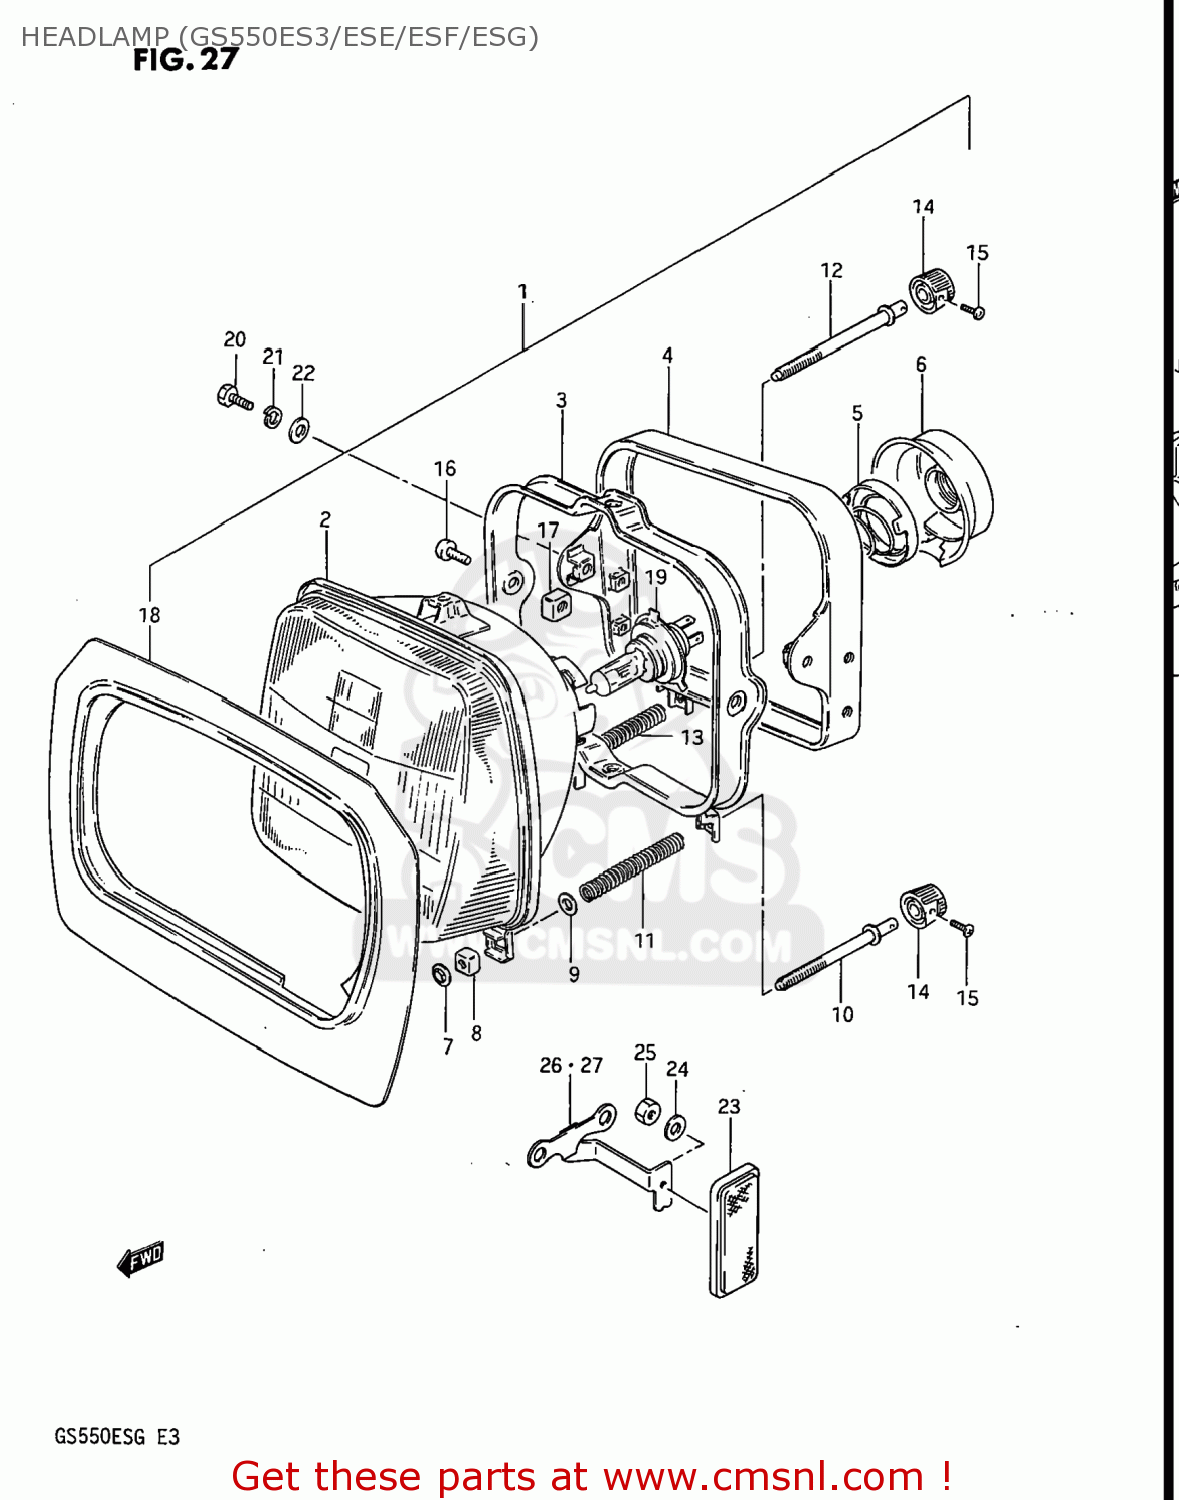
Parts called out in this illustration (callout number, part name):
1	LAMP ASSEMBLY,HEAD
2	LAMP UNIT
3	RING,MOUNTING
4	HOUSING,LAMP UNIT
5	HOLDER
6	COVER,HEADLAMP SOCKET
7	NUT,HEADLAMP ADJUSTER
8	NUT,HEADLAMP ADJUSTER
9	WASHER
10	SCREW,HEADLAMP ADJUST
11	SPRING
12	SCREW,ADJUSTING
13	SPRING
14	KNOB,ADJUSTER
15	SCREW
16	SCREW
17	NUT
18	SHADE
19	BULB(12V60/55W,H4)
20	BOLT
21	WASHER,LOCK
22	WASHER
23	REFLEX REFLECTOR,FR SIDE
24	WASHER,5MM
25	NUT ,5MM
26	BRACKET, RH
27	BRACKET, LH
